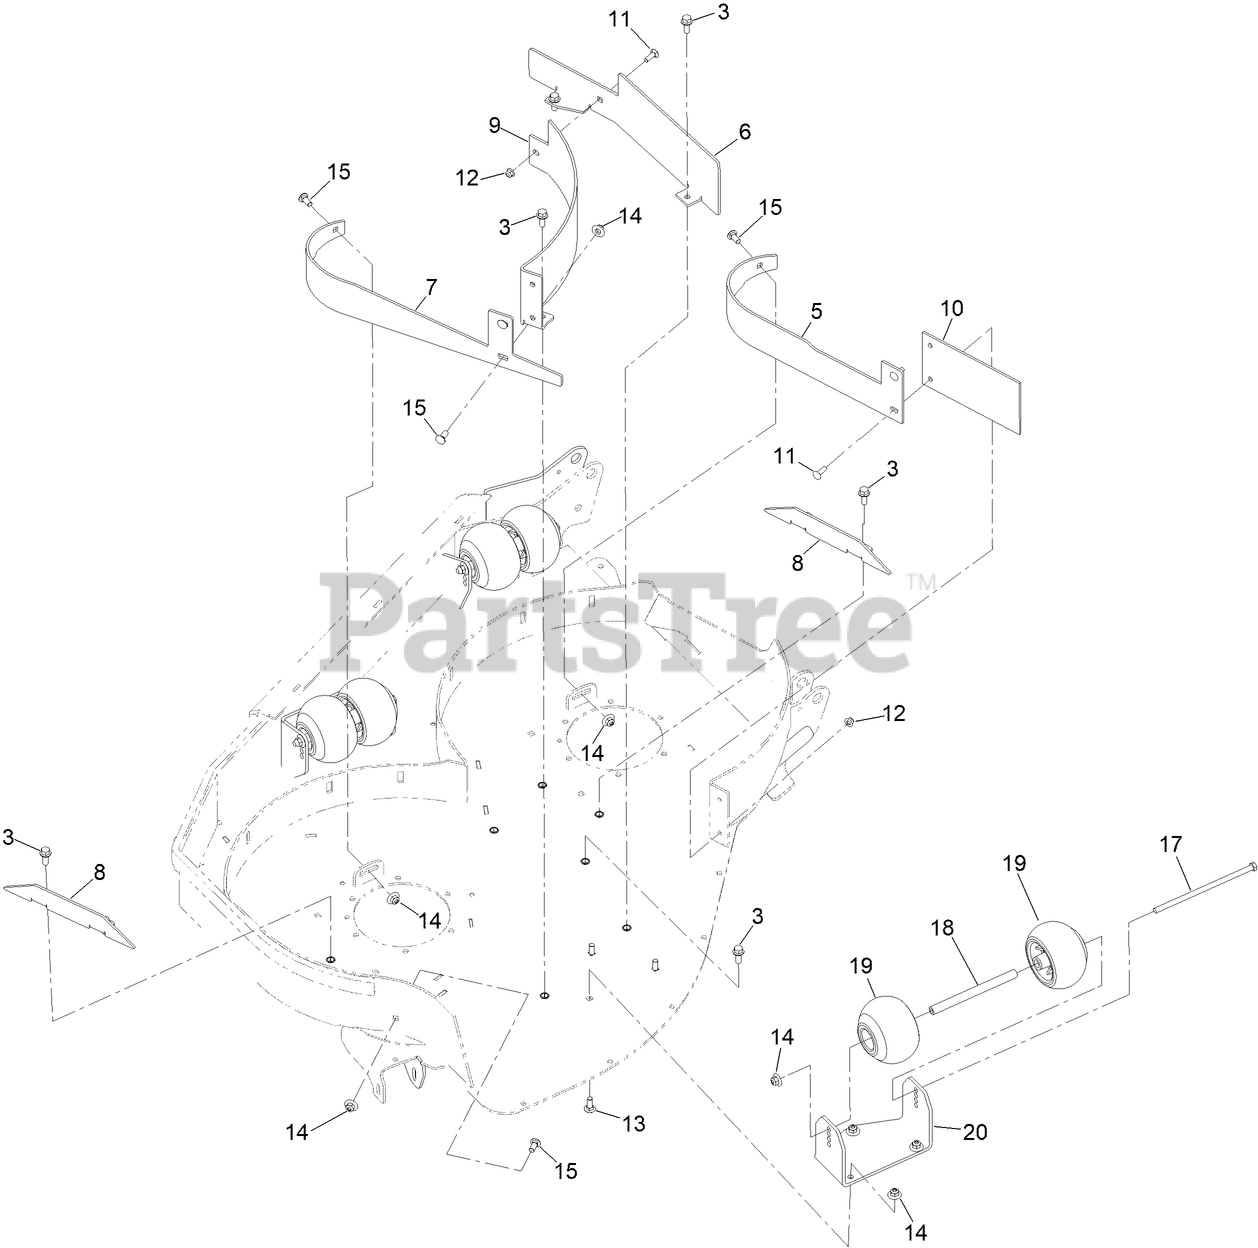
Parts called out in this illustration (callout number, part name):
3	SCREW-HHF
5	BAFFLE-DOGLEG, RH
6	BAFFLE-CTR
7	BAFFLE-DOGLEG, OUTSIDE
8	PLATE-BAFFLE STRAIGHT RH
9	BAFFLE-WING REAR CENTER
10	FLAP-RUBBER
11	SCREW-CARR
12	NUT-HF, NI
13	BOLT-CARR
14	NUT-FLANGE, NI
15	BOLT-CARR
17	SCREW-HH
18	SPACER-WHEEL
19	ROLLER-SCALP, ANTI
20	PLATE-REAR AS BRACKET
